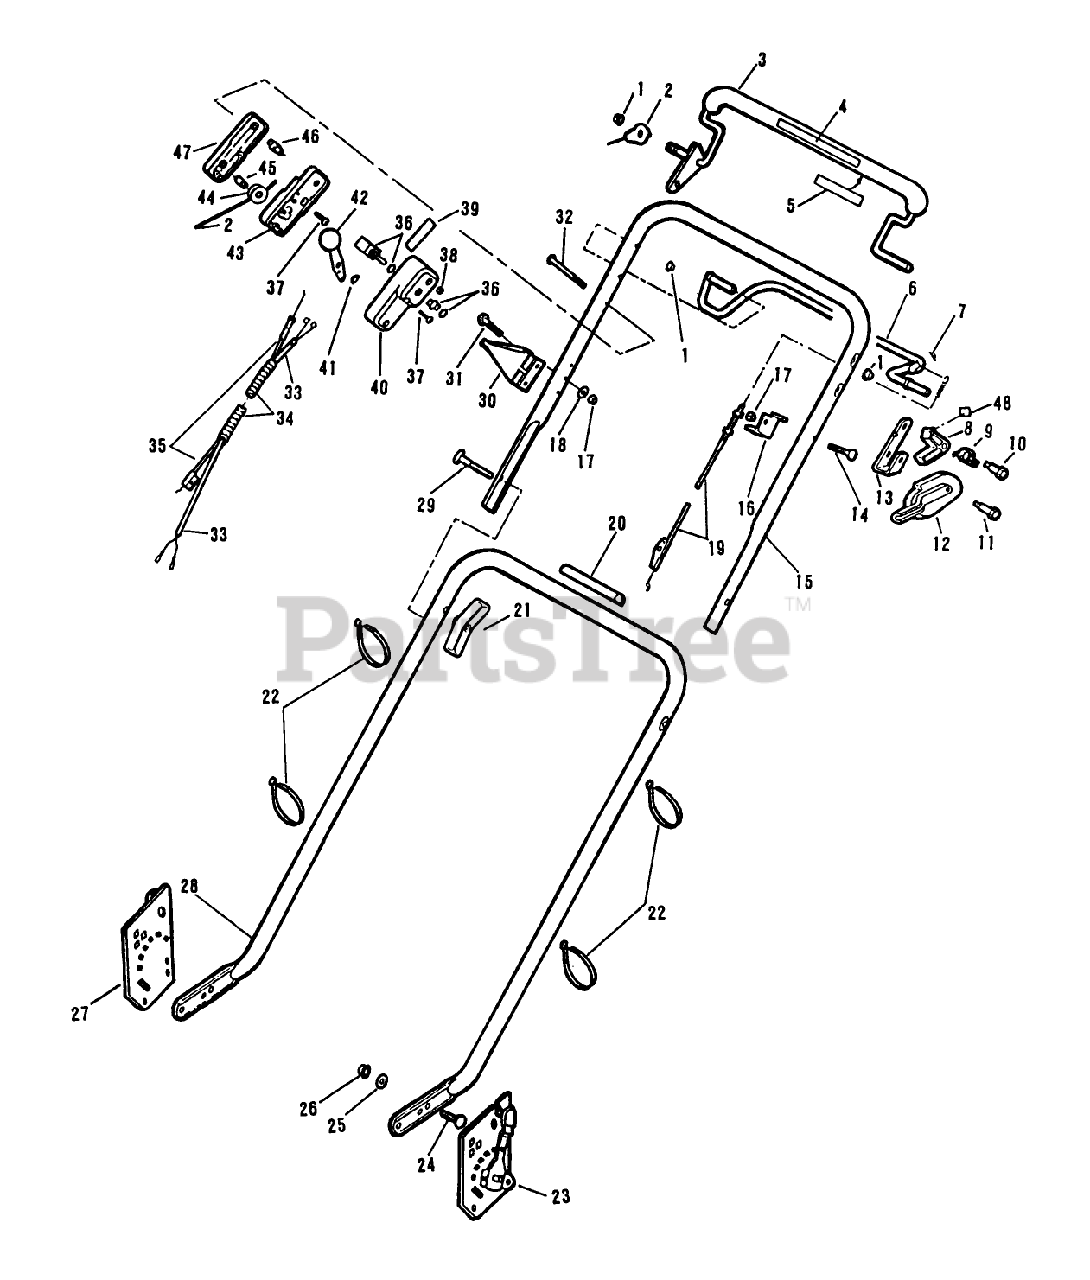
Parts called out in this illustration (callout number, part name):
2	CONTROL CABLE WES
11	BOLT
14	SCREW - USE 137-3042
16	ANCHOR C'DUIT TRO
17	LOCKNUT E
18	WASHER
19	CABLE - CONTROL
21	NUT-WING
26	NUT WING
32	SCREW
35	CABLE TH'TTLE WES
37	SCREW
38	NUT C/LOCK E
41	WASHER-SPRING
42	LEVER&KNOB AY WES
44	PULLEY PL
45	PIN SKF
46	COLUMN
47	OUTER CONTROL CASE
